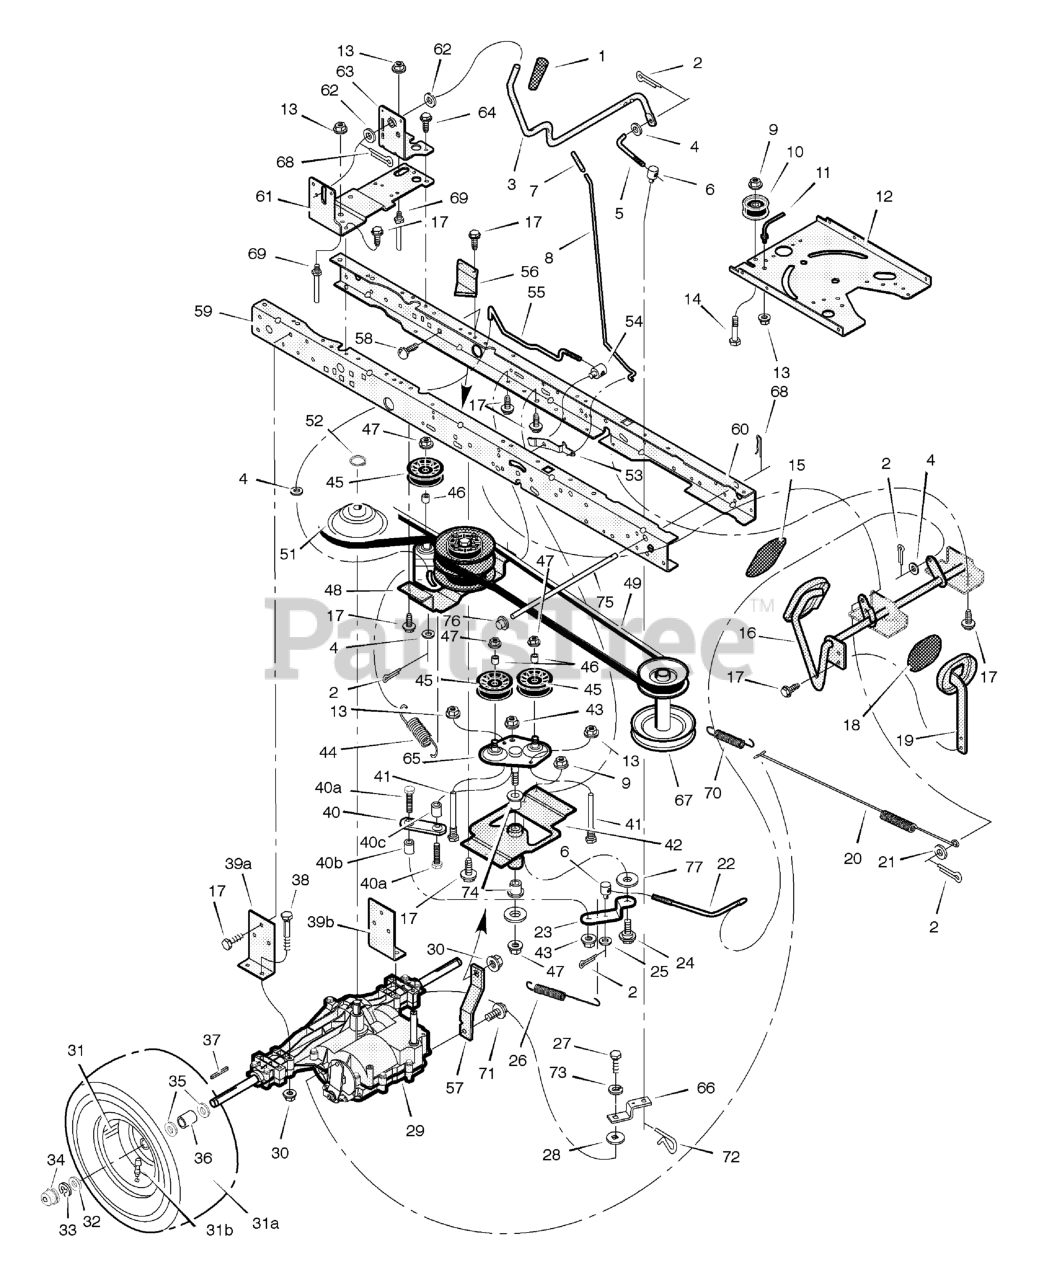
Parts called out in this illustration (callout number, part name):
1	Grip, Shift
2	Pin, Cotter
3	Lever, Shift
4	Washer
5	Link, Shifter
6	Nut, Adjuster
8	Rod, Parking Brake
9	Nut
10	Pulley, Idler
11	Guide, Belt
12	Plate, Steering
13	Nut
14	Bolt, Hex
15	Pad, Motion Drive
16	Assembly, Speed Control
17	Screw, Self Tapping
18	Pad, Brake Pedal
19	Assembly, Brake Pedal
20	Spring, Extension
21	Washer
22	Rod, Speed Control
23	Bellcrank
24	Bolt, Shoulder
26	Spring, Extension
27	Screw, Cap
29	Transaxle **
30	Nut
31	Assembly, Wheel and Tire
31A	Tire *
31B	Stem, Valve
36	Spacer
37	Key, Square
38	Bolt, Hex
39A	Bracket, Right Transaxle
39B	Bracket, Left Transaxle
40	Link, Variator
40A	Bolt, Hex
40B	Spacer, 1/2"
40C	Spacer, 3/4"
41	Guide, Belt
42	Bracket, Front Frame
43	Nut, Lock
44	Spring, Extension
47	Nut
48	Assembly, Variator and Idler
49	Belt, Primary
50	Belt, Secondary
51	Pulley, Transaxle
52	Ring, Snap
53	Latch, Parking Brake
54	Nut, Adjusting
55	Rod, Clutch
56	Bracket, Brake
57	BRACKET, Torque Strap, LH
58	Screw
59	Rail, Right Frame
60	Rail, Left Frame
61	Bracket, Right Shift
62	Washer
63	Bracket, Shift Pivot
65	Assembly, Idler
66	Yoke, Shift
67	Pulley, Stack
68	Pin, Hair
69	Guide, Belt
70	Spring, Return
72	Pin, Hair
75	Rod, Belt Guide
76	Nut, Push-On
